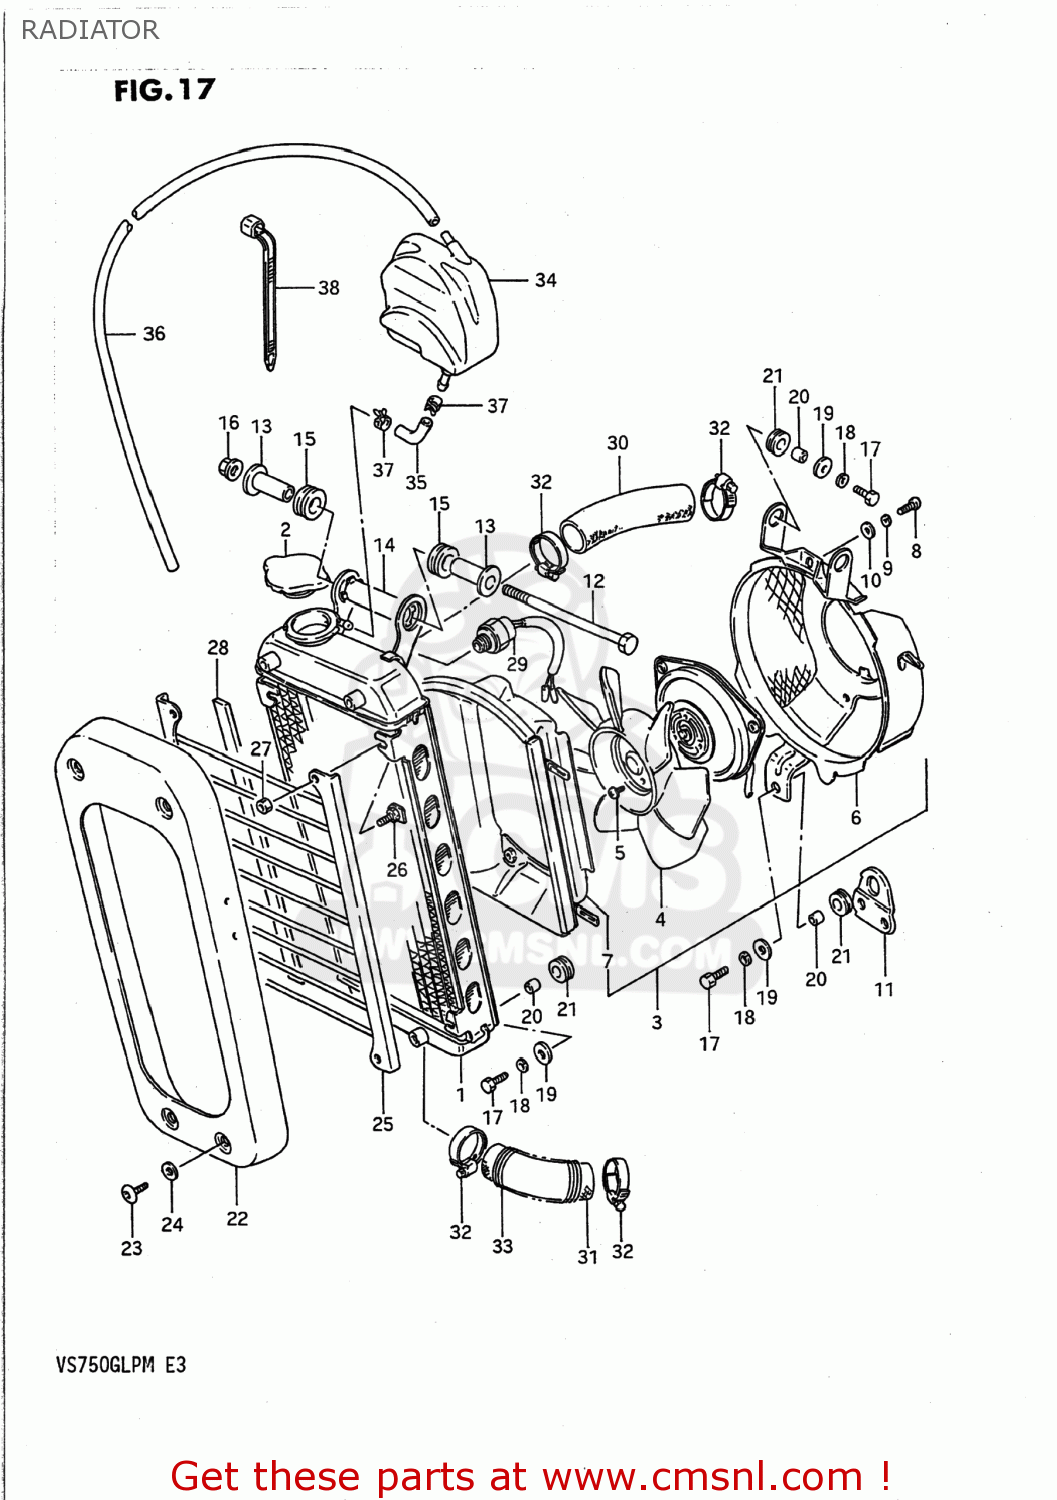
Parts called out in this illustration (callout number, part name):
1	RADIATOR COMP,WATER
2	CAP,RADIATOR
3	FAN ASSEMBLY,RADIATOR
4	FAN
5	BOLT
6	SHROUD,FAN
7	DUCT,FAN
8	SCREW 5X10
9	LOCK WASHER
10	WASHER
11	BRACKET,RADIATOR FAN
12	BOLT 10X135
13	SPACER,RADIATOR CUSHION NO.2
14	SPACER,RDTR CUSH NO.2 OUTER
15	CUSHION
16	NUT 10MM
17	BOLT 6X16
18	WASHER,LOCK
19	WASHER (6.5X18X1.6)
20	SPACER (6X9X8)
21	CUSHION
22	COVER,RADIATOR
23	SCREW
24	WASHER (6.2X14X2)
25	BUMPER COMP,RADIATOR
26	BOLT
27	NUT 5MM
28	CUSHION,RADIATOR BUMPER
29	SWITCH
30	HOSE,RADIATOR INLET
31	HOSE,RADIATOR
32	CLAMP
33	SPRING
34	TANK,RESERVOIR
35	HOSE,RESERVE TANK INLET
36	HOSE,RESERVOIR TANK OVERFLOW
37	CLIP
38	CLAMP(L:125)
39	COVER SET,RADIATOR
